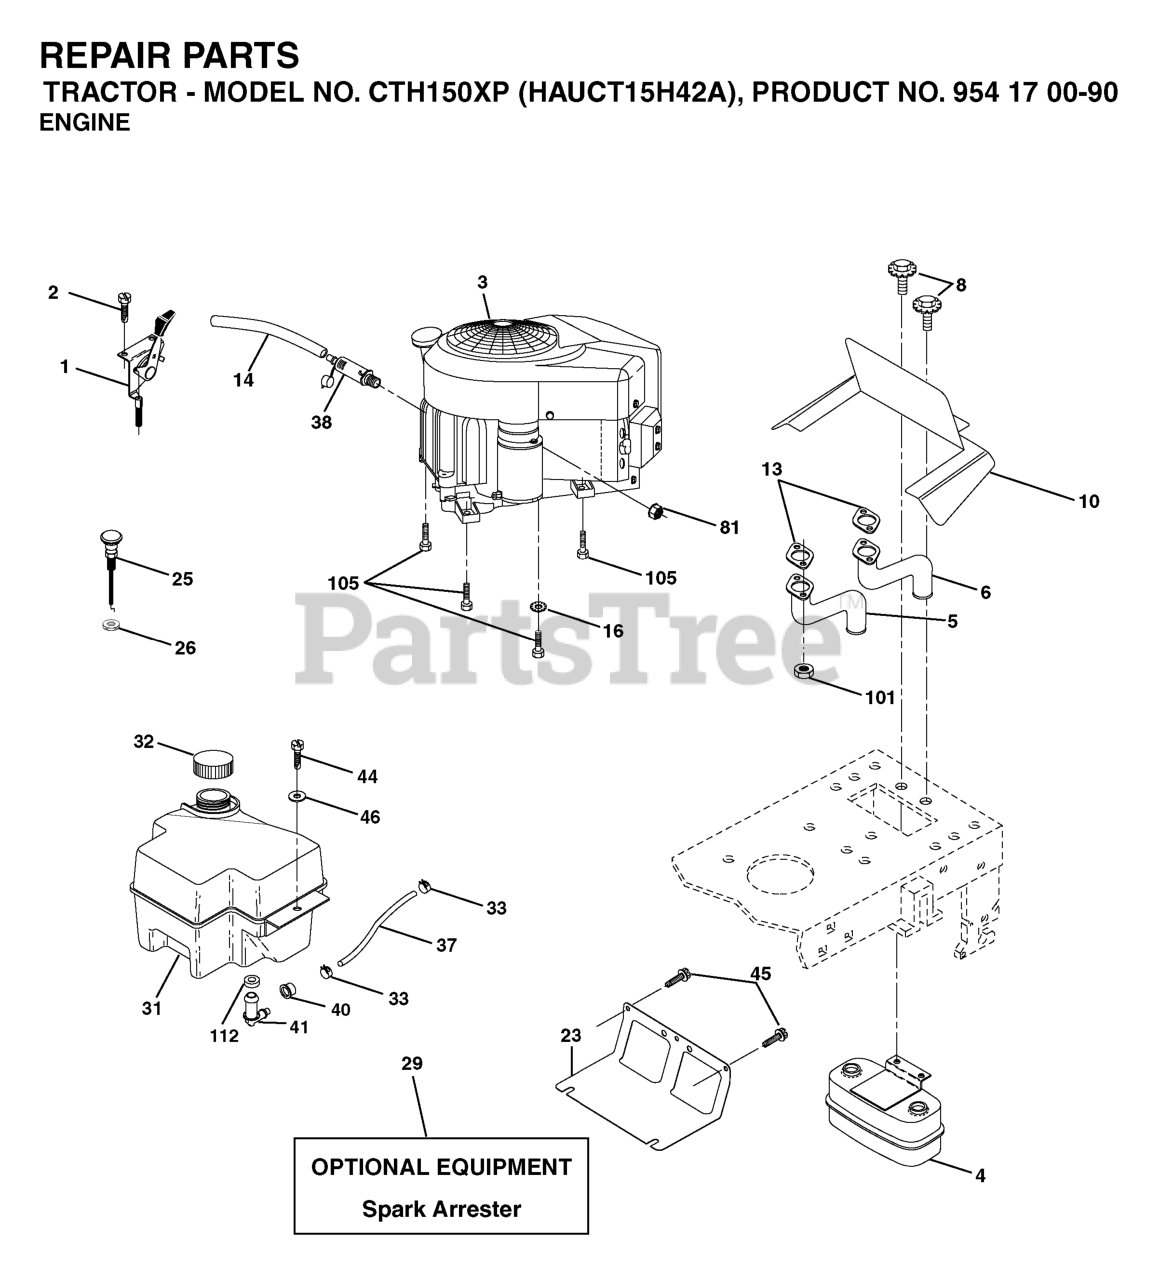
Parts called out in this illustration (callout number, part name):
1	CONTROL, THROTTLE
2	SCREW
4	MUFFLER.TWIN.CYL.LOW.TONE
5	EXHAUST TUBE LH KAWI
6	EXHAUST TUBE RH KAWI
8	BOLT.5/16-18UNCX3/4 W/SEMS.BLK
10	RP SHIELD HEAT MUFFLER
13	GASKET.MUFFLER
14	TUBE, DRAIN OIL ASM.
16	LOCKWASHER
23	SHIELD.BROWNING.DBR.GUARD
25	CHOKE CONTROL
26	Nut Keps 3/8 - 24 UNF
29	KIT.SPARK ARRESTOR 794945 B&S
31	GAS TANK 2GAL
32	FUEL CAP
33	HOSE CLAMP
37	LINE.FUEL.20
40	BUSHING.SNAP.NYL.BLK.
41	STEM FUEL TANK
44	SCREW HEXWSHR 1/4-20X3/4
45	SCREW, 3/8-16X3/4
81	NUT
101	FLANGE NUT
105	SCREW 3/8-16X1
112	BUSHING OUTLET T
